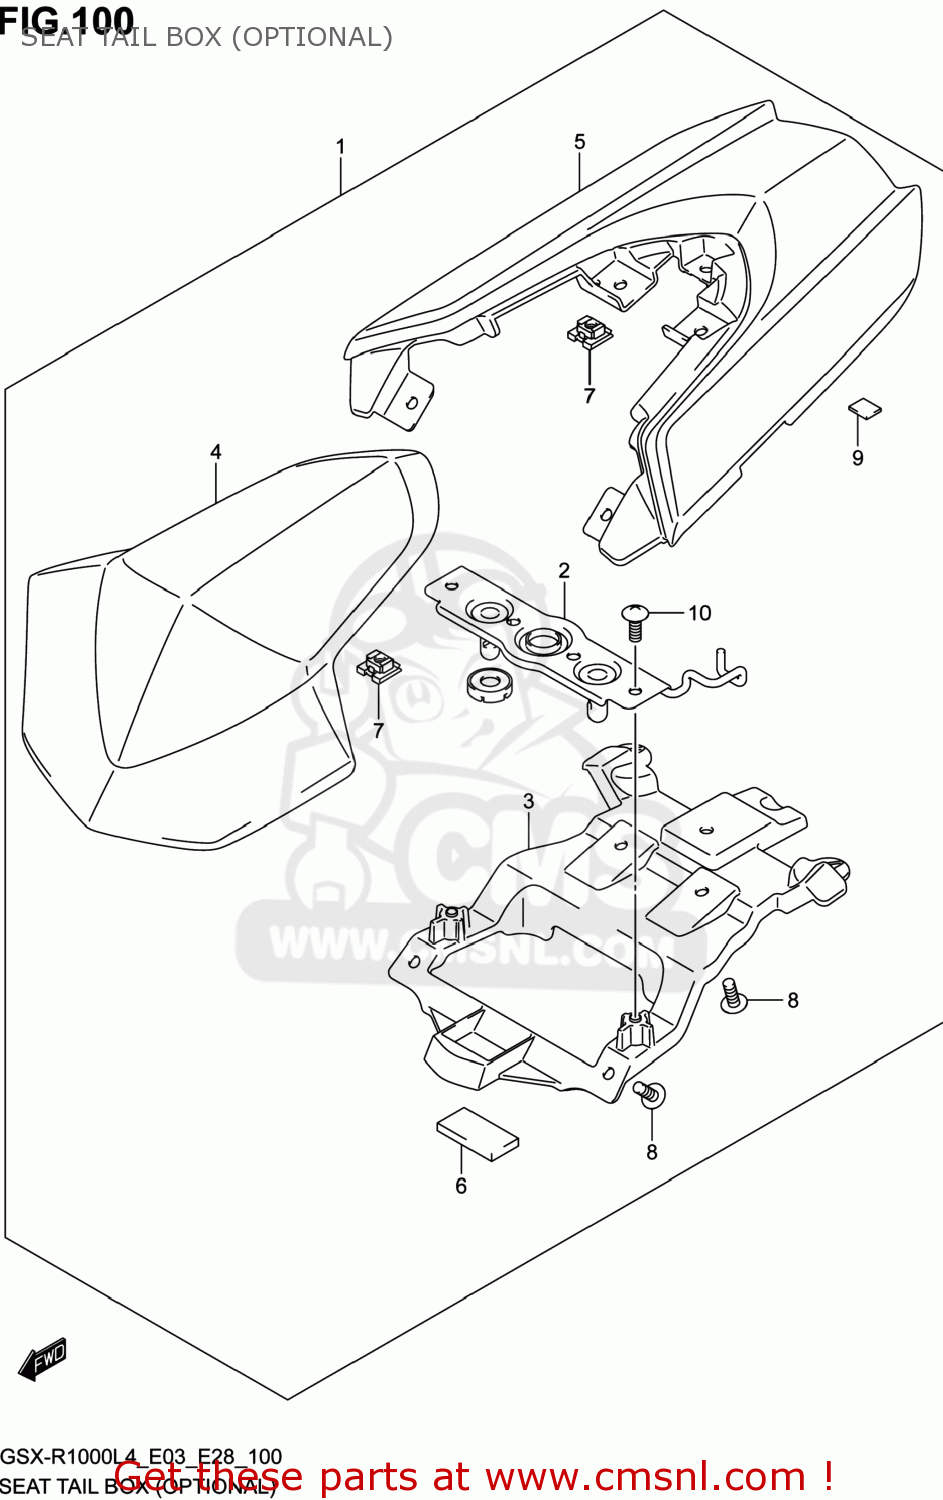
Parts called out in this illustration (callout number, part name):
1	Seat Cowl, Black (2014)
2	STRIKER,SEAT LOCK
3	FRAME,SEAT TAIL BOX
4	BOX,SEAT TAIL FR
5	BOX,SEAT TAIL RR
6	CUSHION,SEAT TAIL BOX
7	NUT
8	SCREW
9	CUSHION,SEAT TAIL COVER LWR FR
10	SCREW
